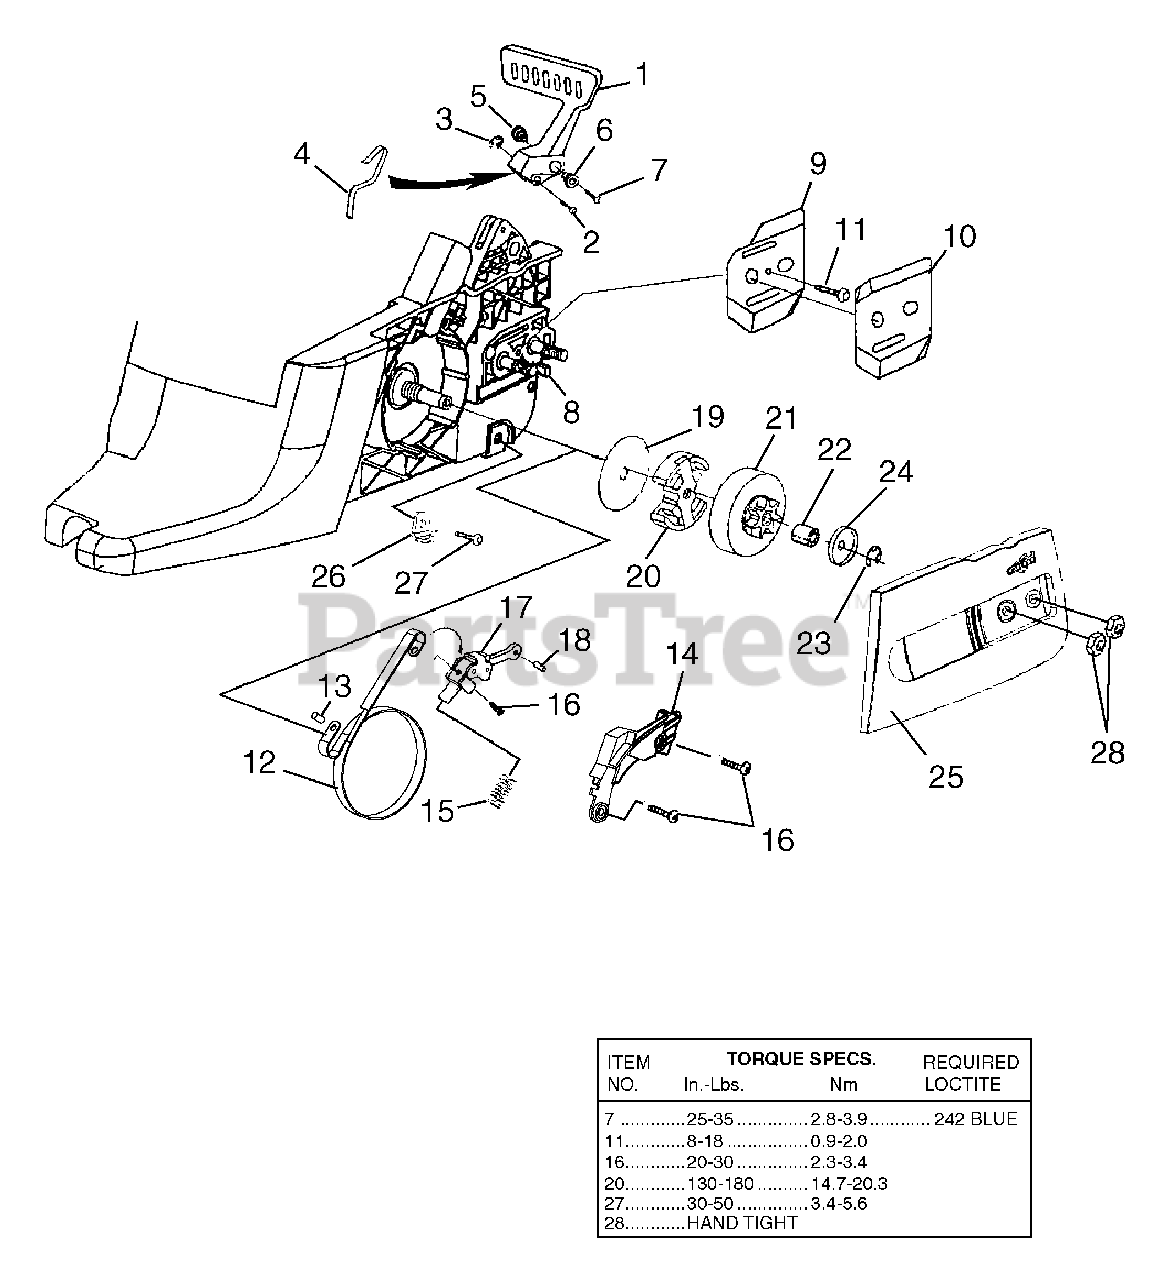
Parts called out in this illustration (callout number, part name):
1	HAND GUARD
2	HAND GUARD ACTUATING PIN
3	RETAINING RING
4	HANDGUARD SPRING
5	PIVOT, L.H.
6	PIVOT, R.H.
7	SCREW (8-32 x 5/8 in.)
8	ADJUSTING PIN
9	GUIDE BAR PLATE
10	GUIDE BAR PLATE
11	SCREW (6-19 x 1/2 in.)
12	BRAKE BAND
13	ROLL PIN
14	CHAIN BRAKE COVER
15	COMPRESSION SPRING
16	SCREW (8-16 x .320)
17	CHAIN BRAKE LINK
18	ROLL PIN
19	THRUST WASHER
20	CLUTCH & HARDWARE
21	DRUM SPROCKET (.375 PITCH)
22	NEEDLE BEARING
23	RETAINING RING
24	CUPPED WASHER
25	DRIVE CASE COVER ASSEMBLY
26	CHAIN CATCHER
27	SCREW (10-24 x 1/2 in.)
28	HEX NUT
